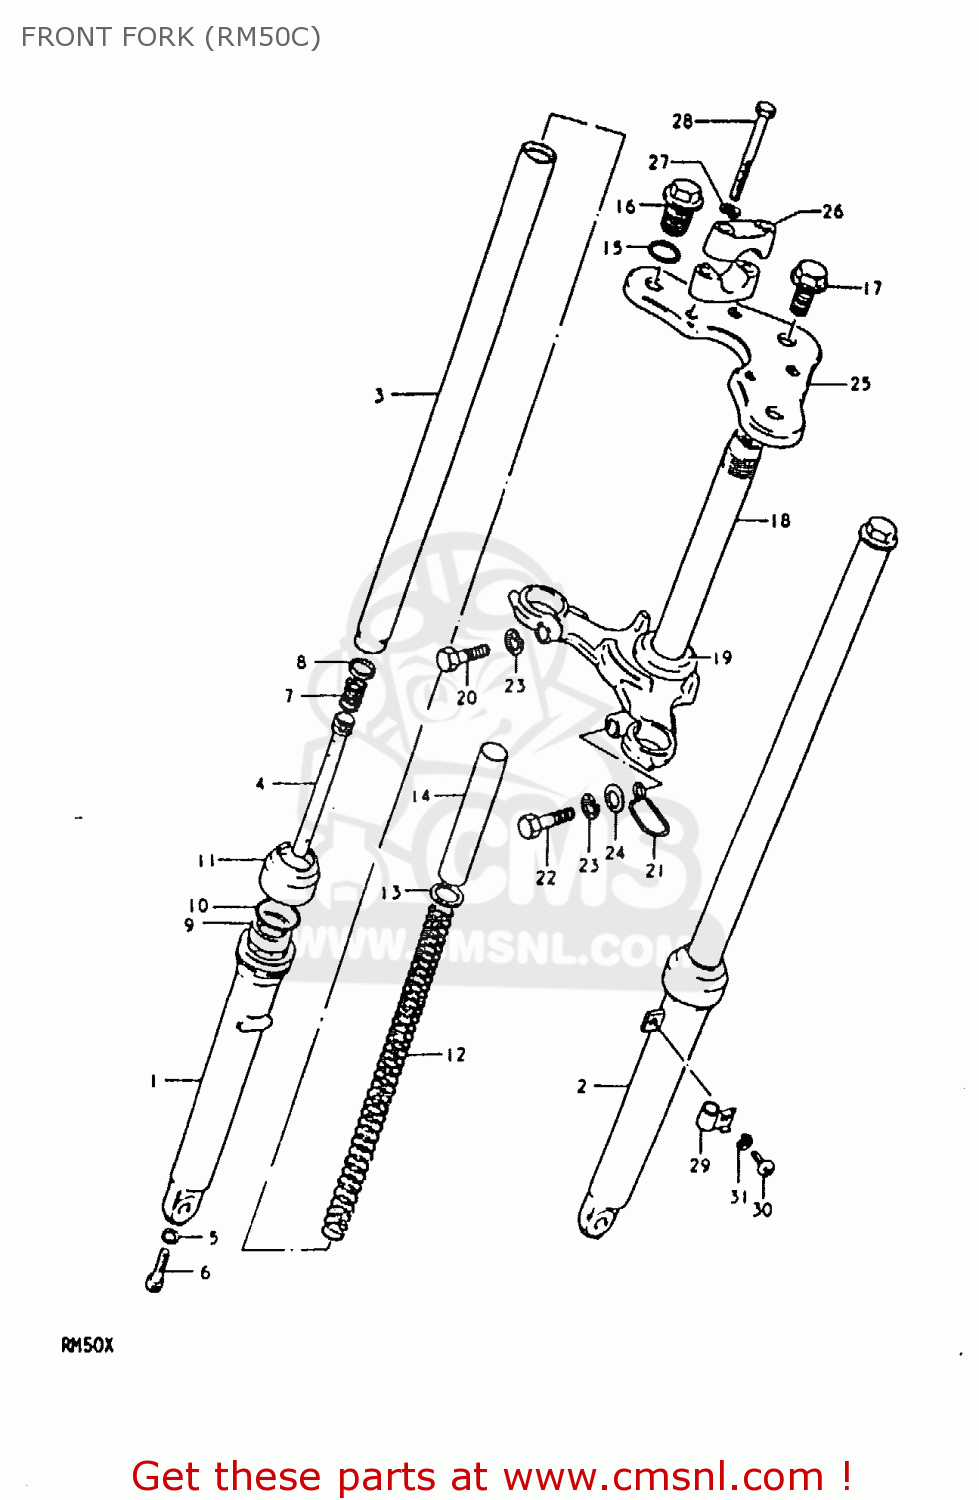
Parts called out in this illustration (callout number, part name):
1	TUBE,OUTER,RIGHT
2	TUBE,OUTER,LEFT
3	TUBE,FORK,INNER
4	CYLINDER,FRONT FORK
5	GASKET (NAS)
6	BOLT
7	SPRING,REBOUND
8	RING,PISTON
9	OIL SEAL,FRONT FORK
10	CIRCLIP,FORK OIL SEAL
11	DUST SEAL
12	SPRING
13	JOINT,SPRING
14	SPACER,SPRING
15	O-RING,FORK INNER TUBE
16	CAP
17	BOLT
18	STEM,STEERING
19	RACE,STEERING OUTER LWR
20	BOLT 10X30
21	CLAMP,METER CABLE
22	BOLT,M10X1.25X
23	LOCK WASHER
24	WASHER
25	HEAD,STEERING STEM
26	HOLDER,HANDLE UPR
27	LOCK WASHER
28	BOLT 8X55
29	CLIP,CABLE
30	SCREW
31	LOCK WASHER
